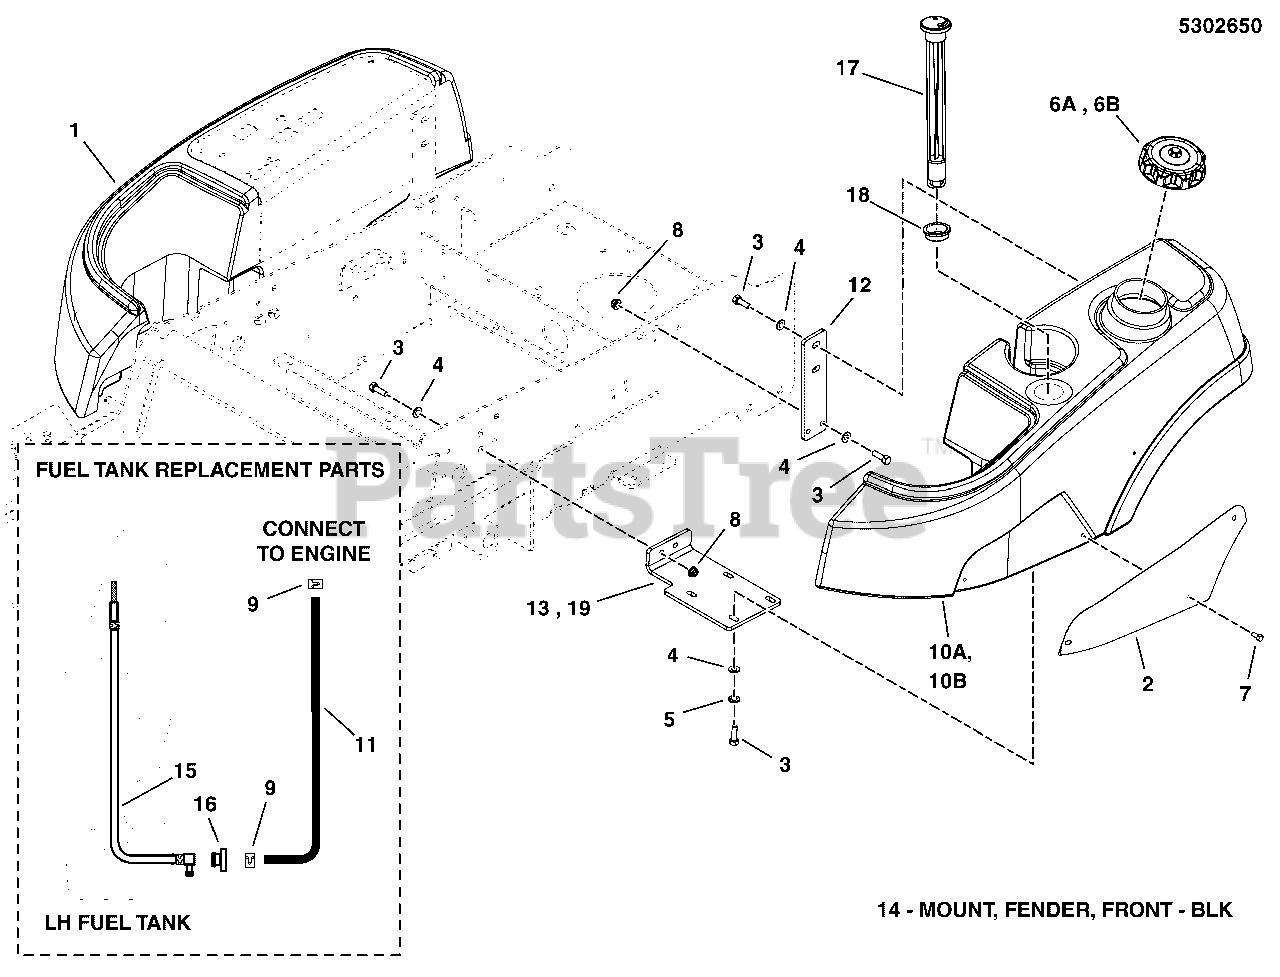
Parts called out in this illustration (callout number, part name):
1	TANK, FENDER, CONZ, RH
2	PLATE,FUEL TANK BADGE
3	BOLT, 5/16-18 X 3/4 GD5
4	WASHER, 5/16" SAE
5	WASHER, 5/16 LOCK YZ
7	SCREW, #10-24 X 3/8 ALLEN BHBZ
8	NUT, 5/16-18 HEX NYLOCK FLANGE
9	CLAMP, HOSE, EXTERNAL, 1/2 - RED
11	HOSE, 1/4" FUEL, 20.00"
12	MOUNT, FUEL TANK, REAR - ORN
13	MOUNT, FUEL TANK, FRONT - BLK
15	PICKUP TUBE ASM, FUEL TANK (SV)
16	BUSHING-FUEL TANK RED RUBBER (SV)
17	FUEL GAUGE (SV)
18	GROMMET (SV)
19	MOUNT, FENDER, FRONT - BLK
